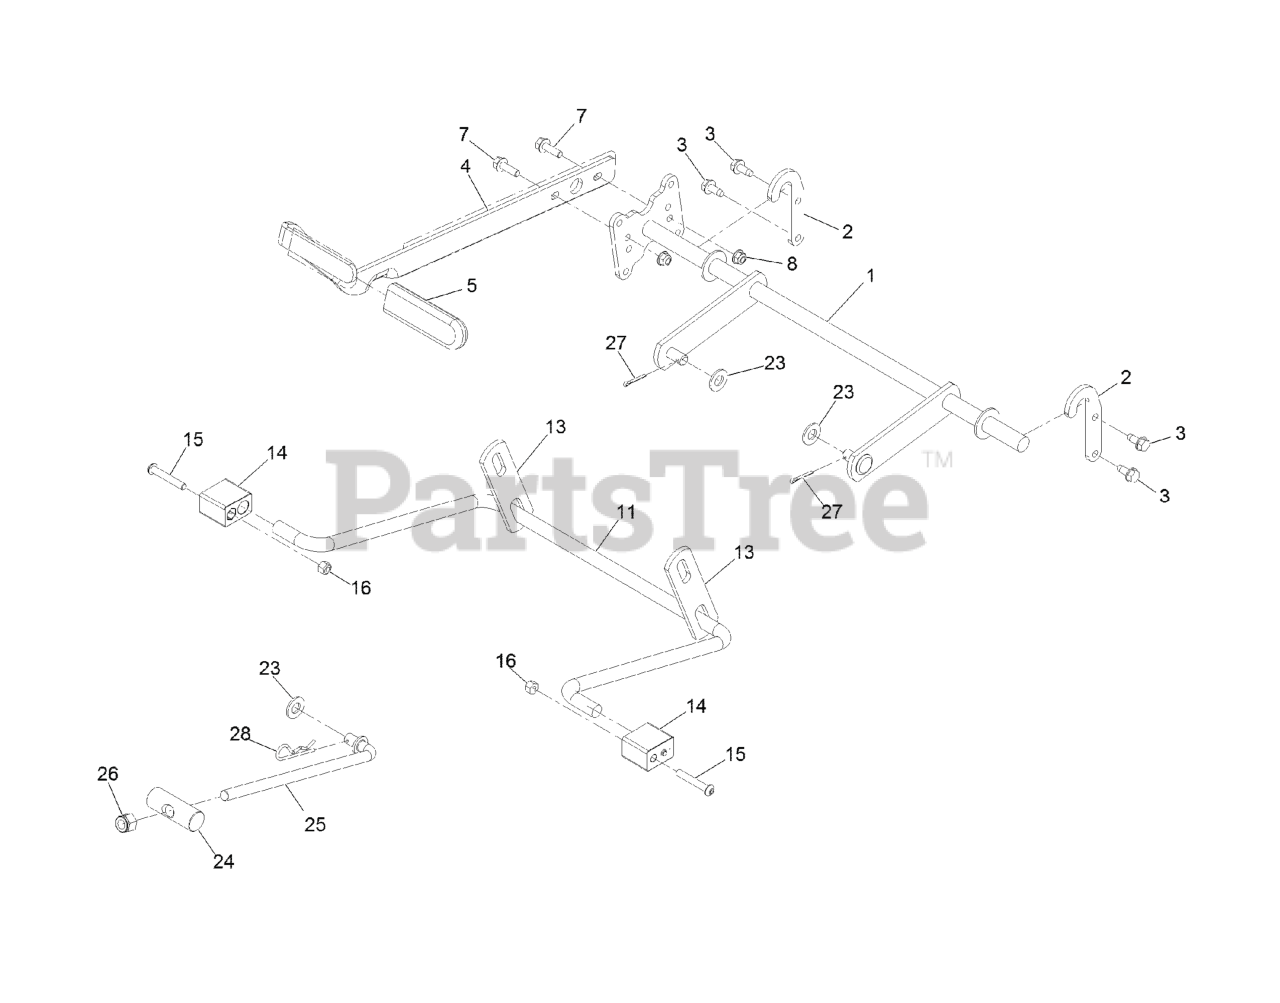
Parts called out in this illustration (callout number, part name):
1	LIFT-DECK, NARROW
2	BRACKET-LIFT
3	Screw-HWH 5/16-18 X 3/4 Tf
4	HANDLE-DECK LIFT
5	GRIP-LEVER
7	SCREW-HHF
8	NUT-HF, NI
11	ARM-LIFT, REAR
13	LINK-LIFT
14	BLOCK-PIVOT
15	SCREW-HSBH
16	NUT-LOCK, NI
23	WASHER-FLAT
24	PIN-PIVOT
25	ROD-MOUNT, DECK
26	NUT-HEX
27	PIN-COTTER
28	PIN-COTTER
